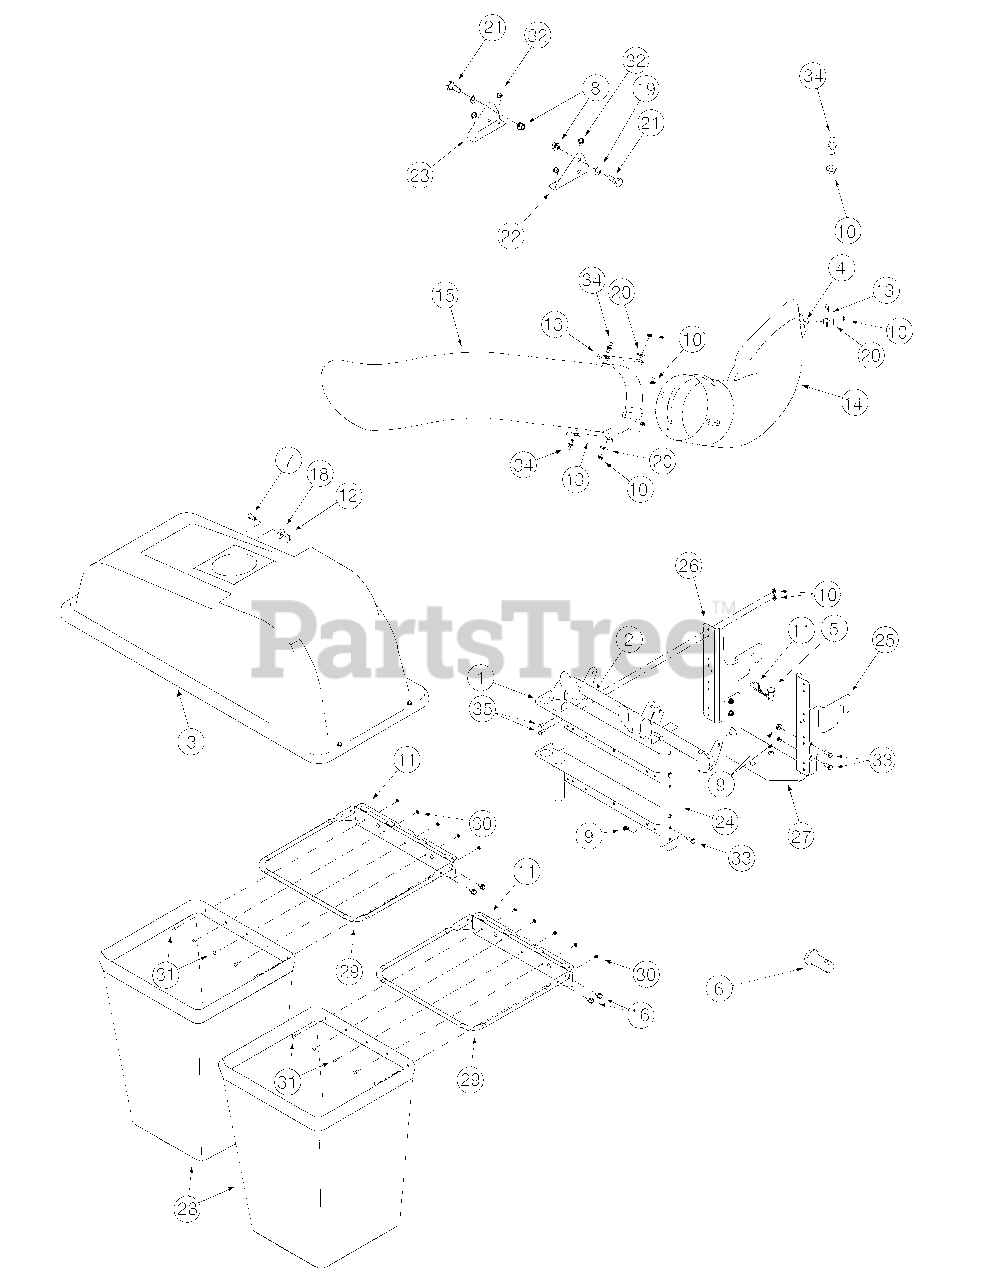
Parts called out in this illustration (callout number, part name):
3	Grass catcher Cover Assembly
4	Screw 1/4-20 x 1"
6	Clevis Pin (on older model tractors)
8	Lock Nut 7/16-20
9	Lock Nut 5/16-18
10	Hex Flange Lock Nut, 1/4-20
11	Hairpin Clip
14	Discharge Chute 38"/42" Bag
16	Self-Tapping Screw 5/16-18
21	Shoulder Screw
22	Supt. Bracket RH
23	Supt. Bracket LH
28	Catcher Bag
30	Hex Sems Nut, #10-24
31	Machine Screw, , #10-24 x .5
32	AB Screw 5/16-12
33	Hex Head Screw 5/16-18 x .75
34	Grass Catcher Pin 1/4-20
35	Hex Head Screw 1/4-20 x .62
